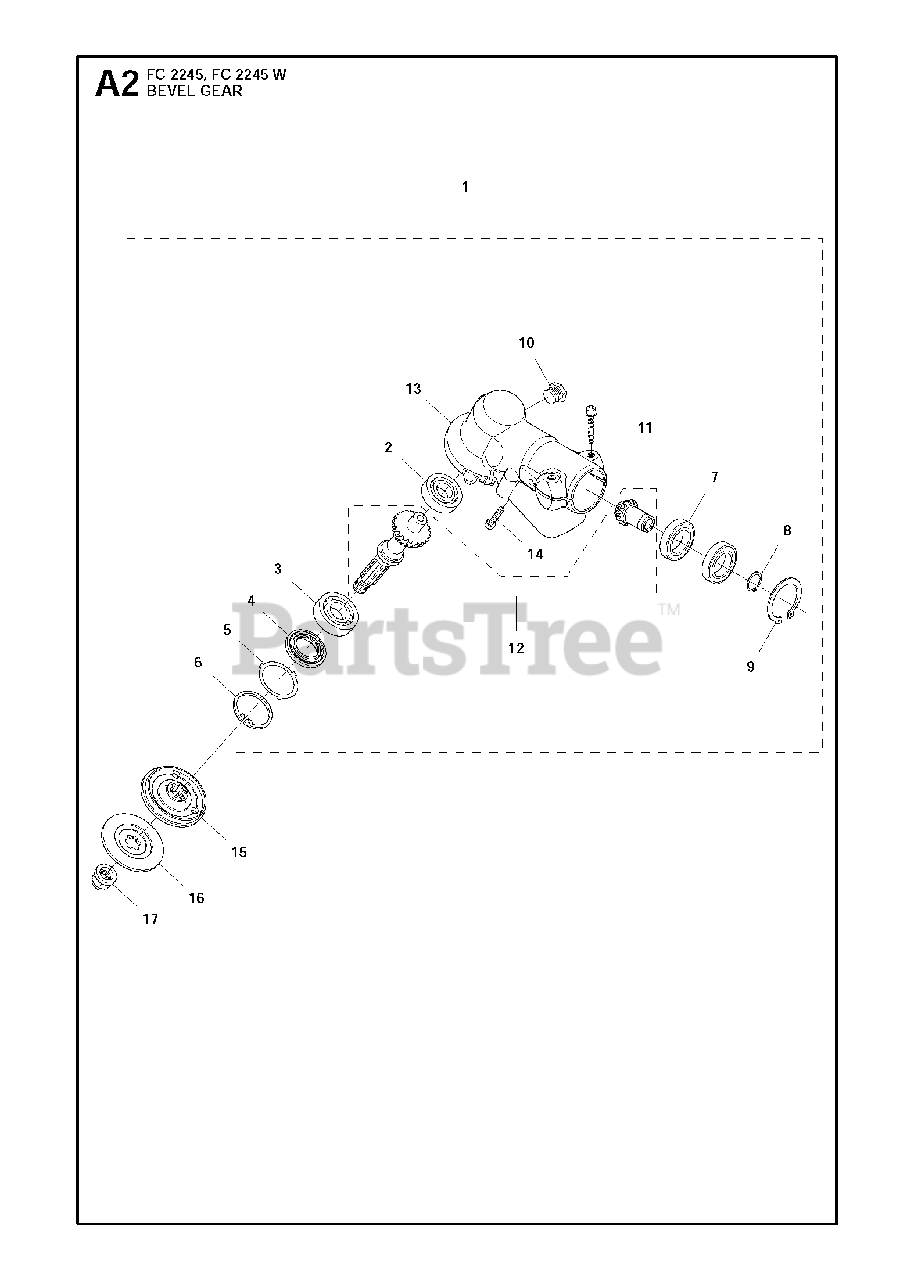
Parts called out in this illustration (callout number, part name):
1	GEAR HOUSING ASSY
2	BALL BEARING
3	BALL BEARING
4	SEAL
5	WASHER
6	RETAINING RING SGH 35
7	BALL BEARING
8	RETAINING RING SGA 15
9	RETAINING RING
10	PLUG
11	SCREW
12	SPARE PARTS KIT
13	GEAR HOUSING
14	SCREW
16	SUPPORT FLANGE
17	NUT BLADE
